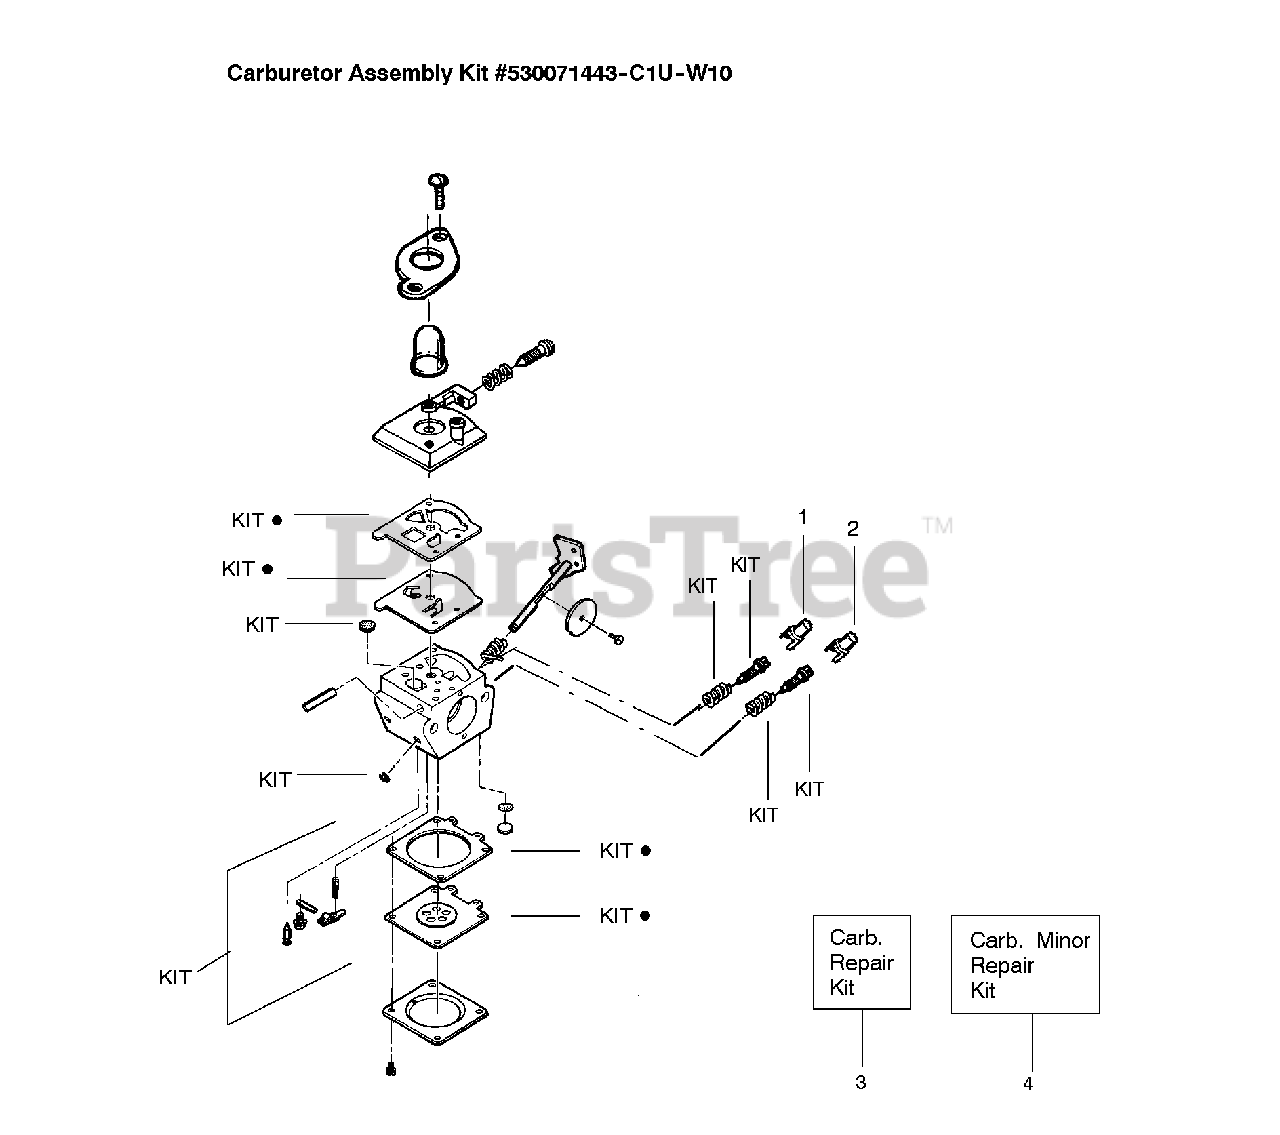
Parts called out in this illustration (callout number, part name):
1	Limiter Cap (low)
2	Limiter Cap (high)
3	Kit-Carburetor Repair
4	Kit-Carburetor Minor Repair
530071443	Carburetor Assembly (C1U-W10)
